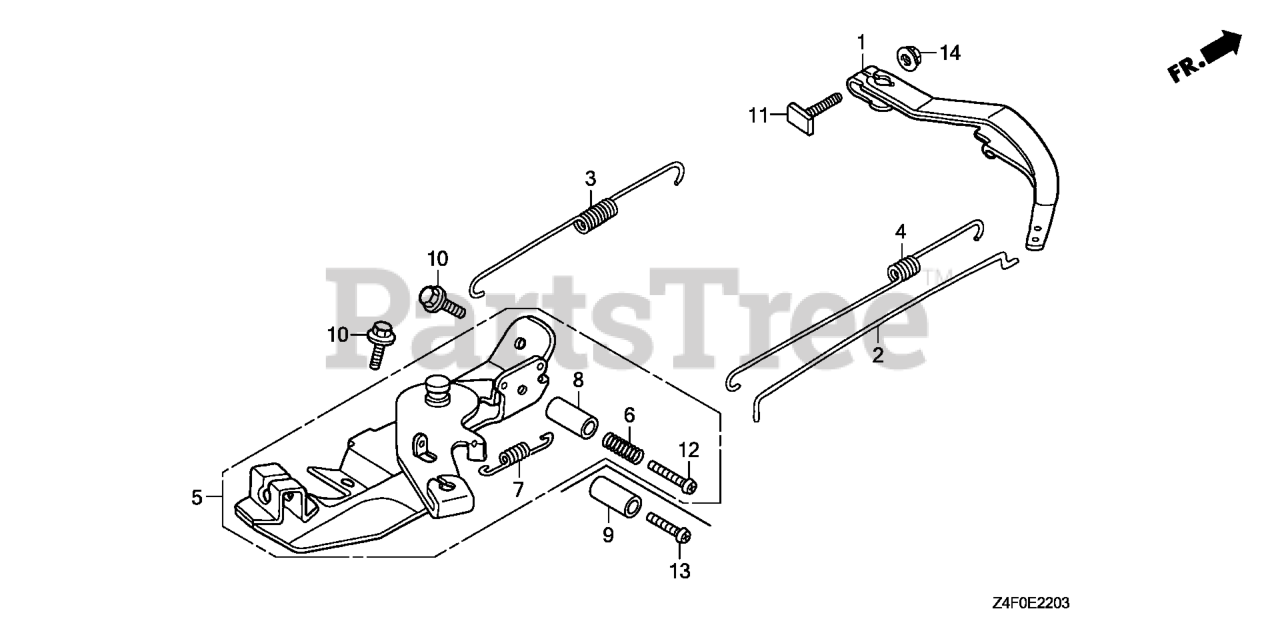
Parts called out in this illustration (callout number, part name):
1	ARM, GOVERNOR
2	ROD, GOVERNOR
3	SPRING, GOVERNOR
4	SPRING, THROTTLE RETURN
5	CONTROL ASSY.
6	SPRING, CONTROL ADJUSTING Use from Engine SN 2327377.
7	SPRING, CABLE RETURN
8	COLLAR, STOPPER
9	COLLAR, STOPPER
10	BOLT, FLANGE (6X12) (CT200)
11	BOLT, GOVERNOR ARM
12	SCREW, RECESSED (5X28)
13	SCREW, RECESSED (5X25)
14	NUT, FLANGE (6MM)
